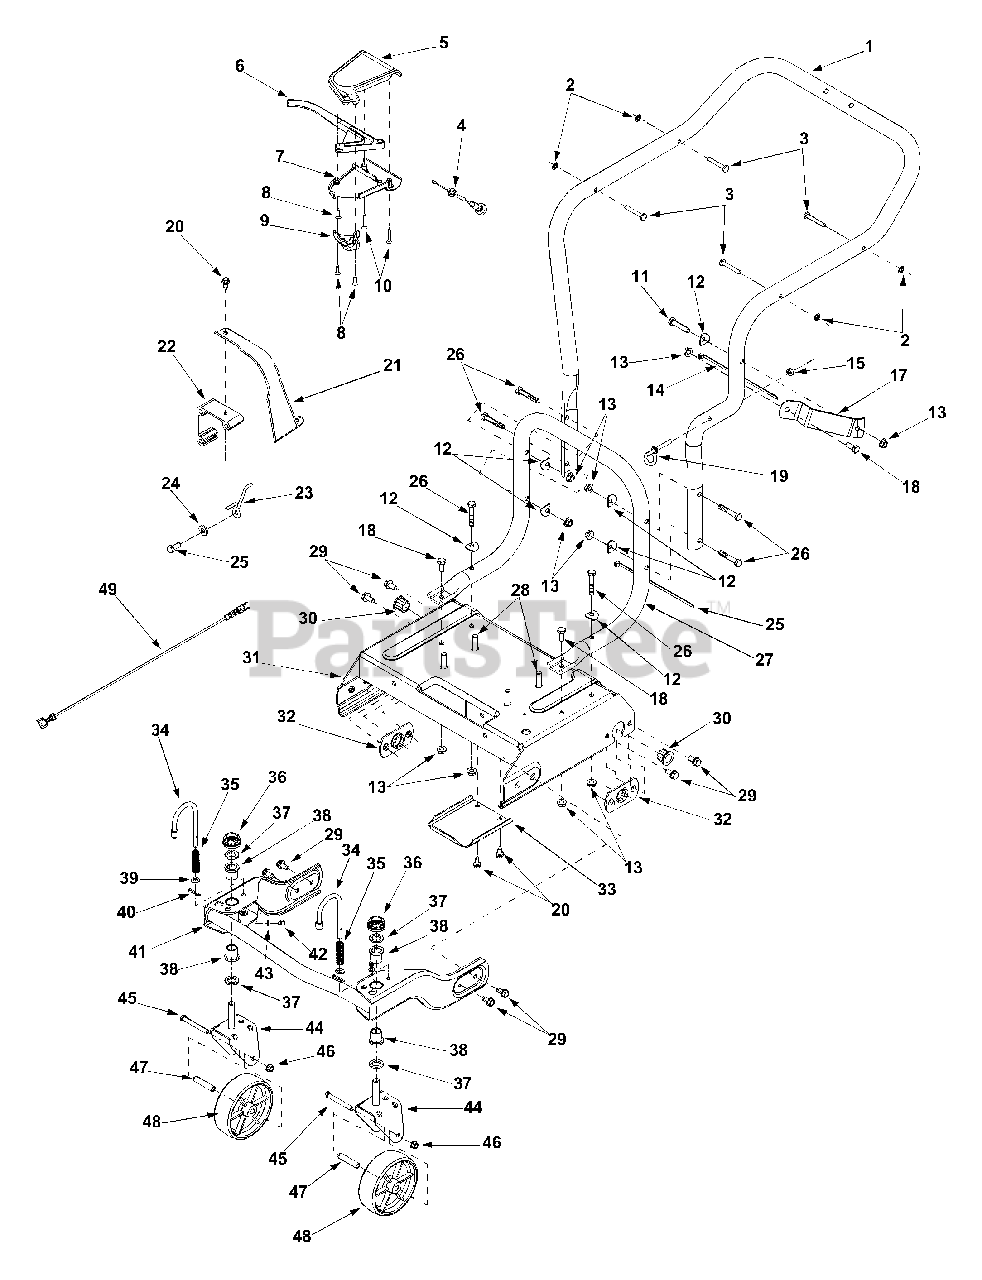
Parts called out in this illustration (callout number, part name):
3	Stud Pin.250 x 1.75
4	Clutch Cable 56"
5	Upper Clutch Cover
6	Drive Lever
7	Lower Clutch Cover
8	Screw #10-12 x.750
9	Mounting Cable Cap
10	Screw #10-16 x 1.25
11	Hex Cap Screw 5/16-18 x 1.50
12	Shoulder Washer.320 ID x.93 OD
13	Hex Flange Lock Nut 5/16-18
14	Cable Tie
15	Hex Nut 1/4-28
18	Hex Cap Screw 5/16-18 x.75
20	Hex Washer Screw 1/4-14 x.625
21	Belt Cover
22	Engine Mounting Adapter
23	Belt Keeper
24	Flat Washer.344 x.75 x.12
25	Hex Cap Screw 5/16-24 x.75
26	Hex Cap Screw 5/16-18 x 1.75
28	Screw 3/8-16 x 1.25
29	Hex Washer Screw 5/16-18 x.625
30	Hex Flange Bearing.631 x.720
35	Compression Spring
37	Flat Washer 5/8 ID x 1.0 OD
38	Flange Bearing.632 ID
39	Flat Washer.330 ID x.630 OD
40	Cotter Pin
42	Grease Fitting 3/16
43	Flat Washer.203 ID x.403 OD
45	Hex Cap Screw 3/8-16 x 3.0
46	Flange Lock Nut 3/8-16
48	Wheel 6.0 x 2.0
49	Adapter Harness Assembly
